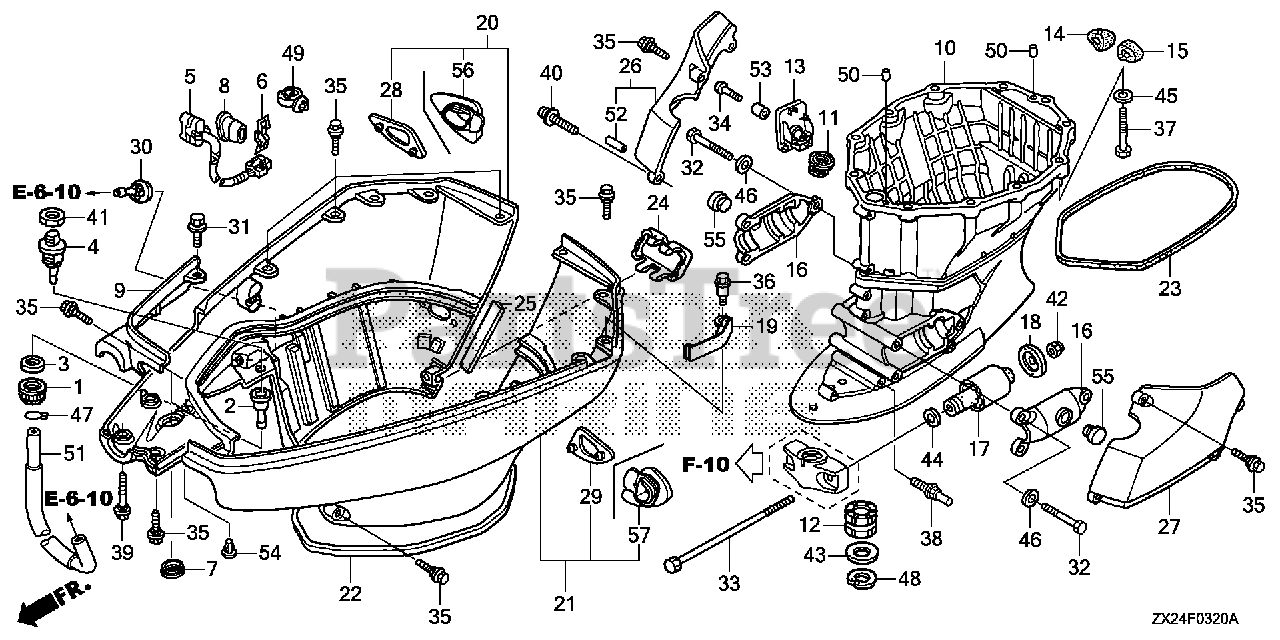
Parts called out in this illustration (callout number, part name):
1	NUT, WATER MOUTH
2	JOINT, WATER HOSE
3	SEAT, WATER MOUTH
4	CAP, WATER JOINT
5	SWITCH ASSY., POWER TILT
6	STAY, POWER TILT SWITCH
7	GROMMET, CASE (LOWER) (C)
8	GROMMET, POWER TILT SWITCH
9	COVER, FR. SEPARATE *NHB14M* (AQUA MARINE SILVER METALLIC)
9	COVER, FR. SEPARATE *NH565* (GRAND PRIX WHITE)
10	CASE, EXTENSION *NHB14M* (AQUA MARINE SILVER METALLIC)
10	CASE, EXTENSION *NH565* (GRAND PRIX WHITE)
11	RUBBER, DRAIN PLUG
13	COVER, DRAIN PLUG *NHB14M* (L) (AQUA MARINE SILVER METALLIC)
13	COVER, DRAIN PLUG *NH565* (L) (GRAND PRIX WHITE)
14	SEAL, R. IDOL PORT
15	SEAL, L. IDOL PORT
16	HOUSING, MOUNTING (LOWER)
17	MOUNT, RUBBER (LOWER)
18	STOPPER, MOUNT (LOWER)
19	COVER, PLUG MAINTENANCE
20	COVER, R. ENGINE (LOWER) *NHB14M* (AQUA MARINE SILVER METALLIC)
20	COVER, R. ENGINE (LOWER) *NH565* (GRAND PRIX WHITE)
21	COVER, L. ENGINE (LOWER) *NHB14M* (AQUA MARINE SILVER METALLIC)
21	COVER, L. ENGINE (LOWER) *NH565* (GRAND PRIX WHITE)
22	SEAL A, COVER (LOWER)
23	SEAL B, COVER (LOWER)
24	CAP, COVER (LOWER) *NHB14M* (AQUA MARINE SILVER METALLIC)
24	CAP, COVER (LOWER) *NH565* (GRAND PRIX WHITE)
25	SEAL C, COVER (LOWER)
26	COVER, R. MOUNTING (LOWER) *NHB14M* (L) (AQUA MARINE SILVER METALLIC)
26	COVER, R. MOUNTING (LOWER) *NH565* (L) (GRAND PRIX WHITE)
27	COVER, L. MOUNTING (LOWER) *NHB14M* (L) (AQUA MARINE SILVER METALLIC)
27	COVER, L. MOUNTING (LOWER) *NH565* (L) (GRAND PRIX WHITE)
28	GROMMET, R. IDLE PORT
29	GROMMET, L. IDLE PORT
30	GROMMET, WATER CHECK
31	BOLT-WASHER (6X25)
32	BOLT, HEX. (10X35)
33	BOLT, HEX. (14X180)
34	SCREW, SPECIAL (6X35)
35	BOLT, SPECIAL (6X17)
36	BOLT, SPECIAL (6X22)
37	BOLT, HEX. (12X50)
38	BOLT, SPECIAL (6X12)
39	BOLT, SPECIAL (6X37)
40	SCREW-WASHER (6X40)
41	NUT, HEX. (16MM)
42	NUT, SELF-LOCK (14MM)
44	WASHER, PLAIN (14MM)
45	WASHER, PLAIN (12MM)
46	WASHER, PLAIN (10MM)
47	CLIP, TUBE (B12.5)
49	CLIP, WIRE HARNESS (25MM)
50	PIN, DOWEL (6X10)
51	TUBE, WATER JOINT
52	COLLAR (6.2X10X25.5)
53	COLLAR, DISTANCE (6X10.5X25)
54	PLUG, HOLE (5MM)
55	RUBBER C, STAND STOPPER
56	GROMMET, R. IDLE PORT
57	GROMMET, L. IDLE PORT
